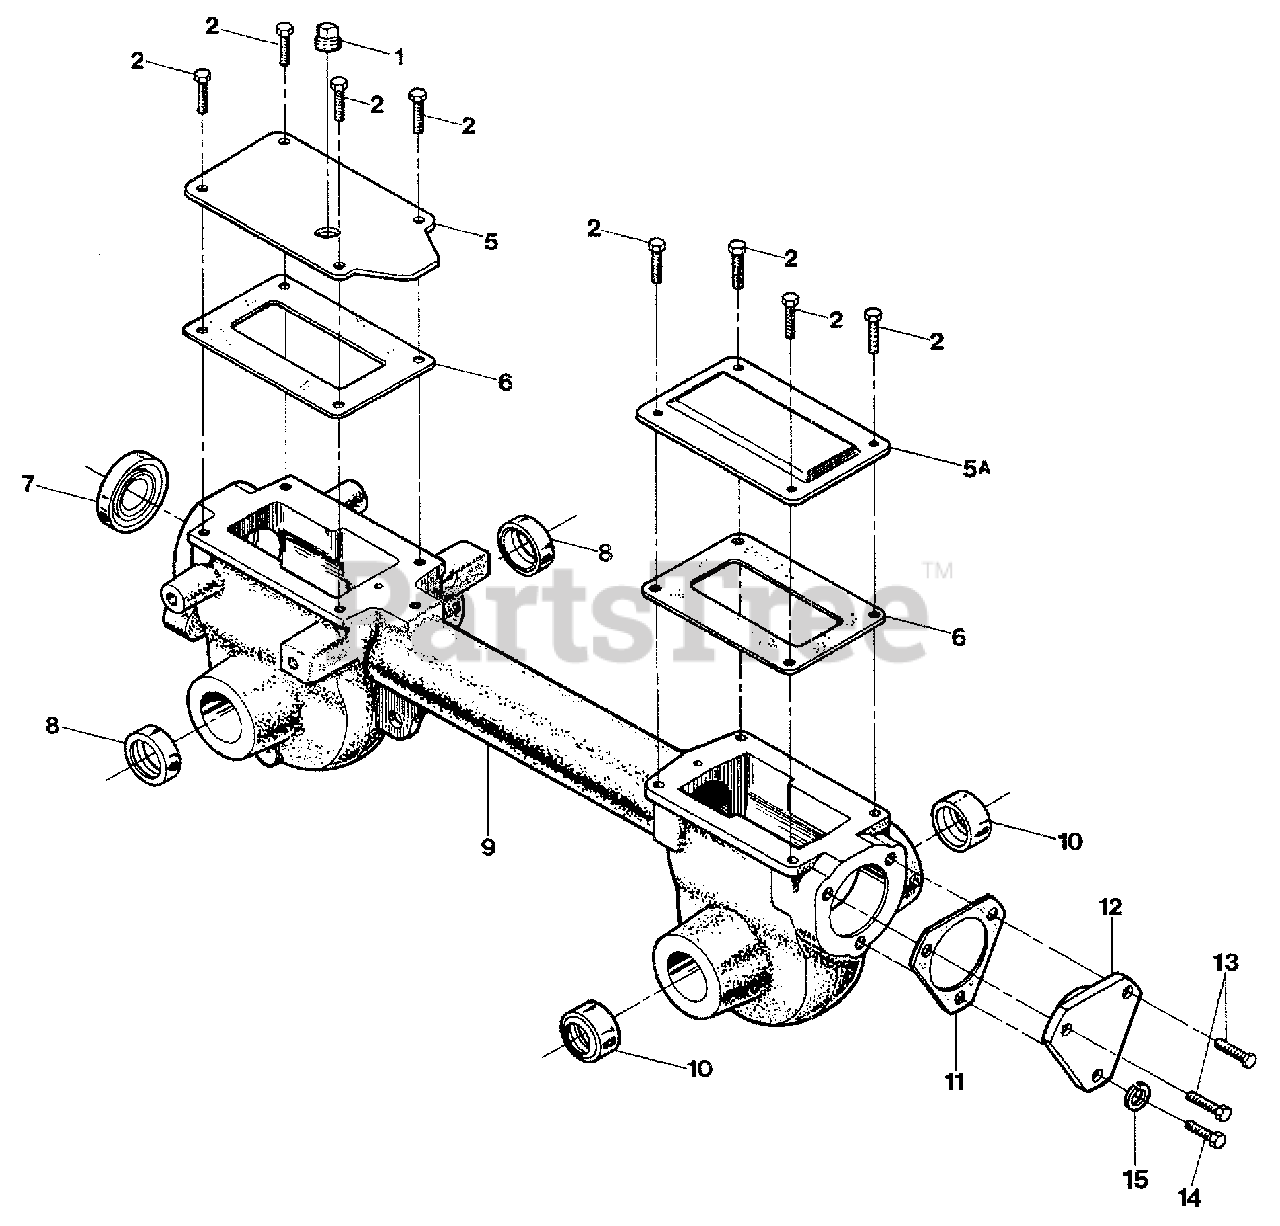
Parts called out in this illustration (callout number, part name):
1	Plug, Transmission Oil Fill
2	Hex Hd. Flange Screw, 5/16-18 x 5/8, Grade 5
5	Front Cover, Transmission
5A	Rear Cover, Transmission
6	Gasket, Housing Cover
7	Oil Seal, Drive Shaft
8	Oil Seal, Wheel Shaft
9	Transmission Housing Assy
10	Oil Seal, Tine Shaft
11	Bearing Cap Gasket, .010" thick
12	Rear Bearing Cap
13	Hex Hd. Flange Screw, 5/16-18 x 1
14	Hex Hd. Flange Screw, 5/16-18 x 3/4
15	Lock Washer, 5/16
